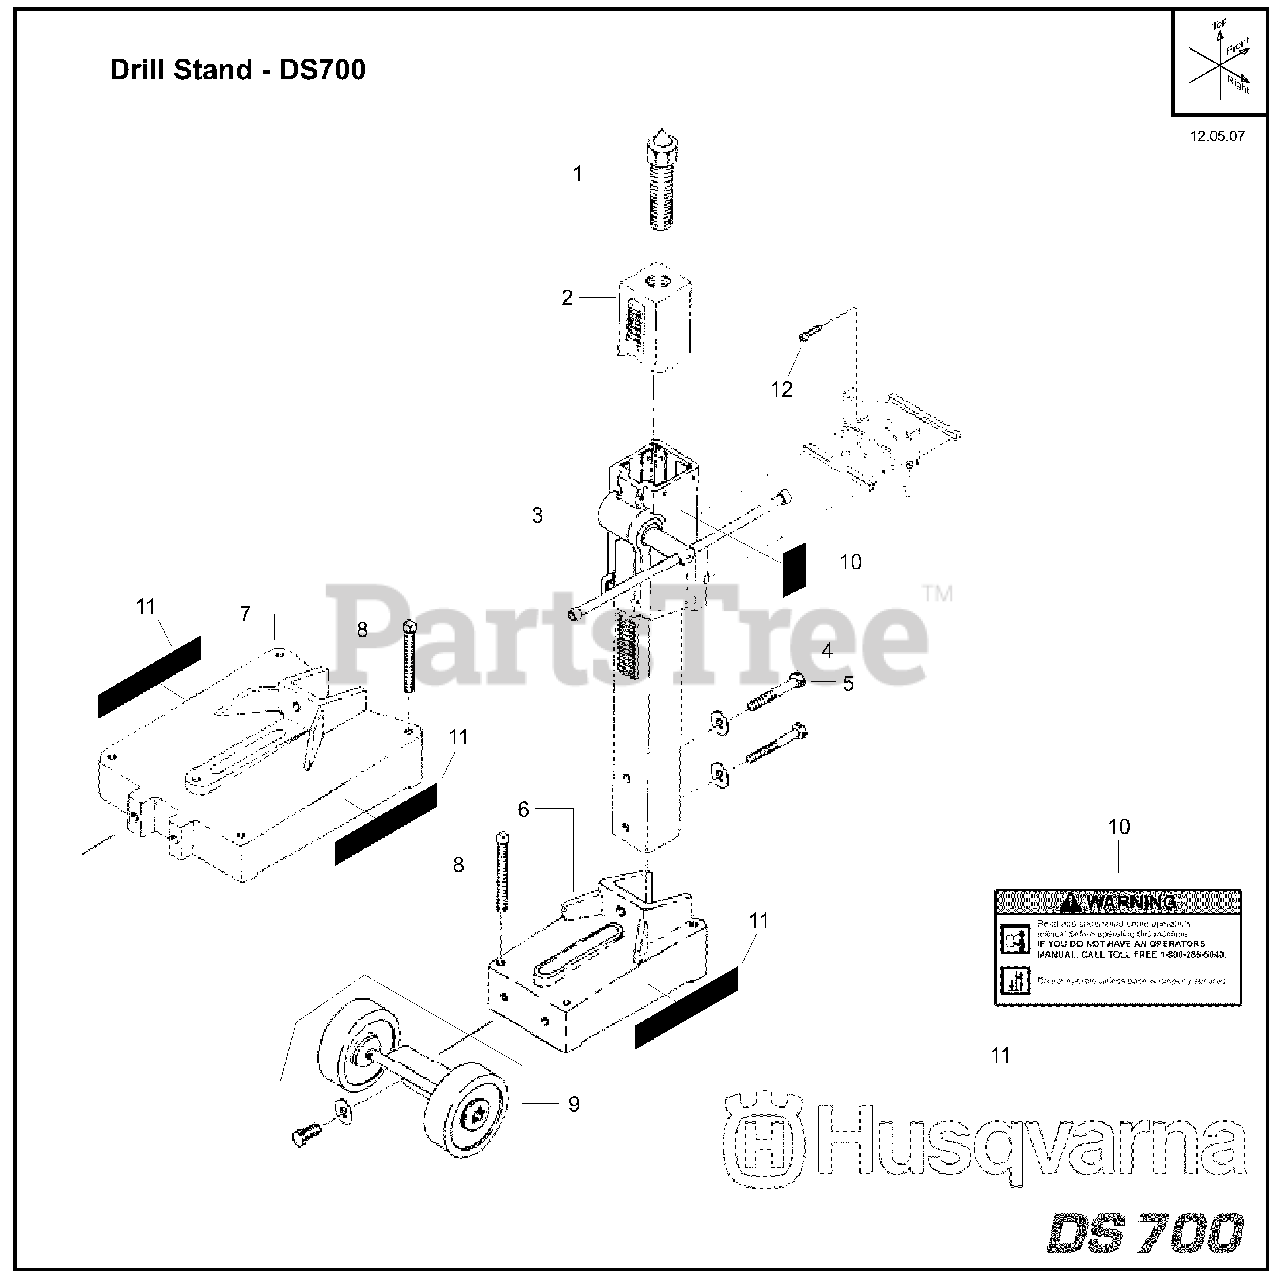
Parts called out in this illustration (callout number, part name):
1	Screw, Ceiling Jack, 1"-8UNC
2	Column w/ Rack - 2-1/2" Sq x 42"
3	Carriage, Slide - compl
4	Washer, Flat 1/2"
5	Capscrew, Hex Hd 1/2-13 x 3.25"
6	Base, Small, DS700 - Husq Orange
7	Base, Large, DS700 - Husq Orange
8	Capscrew, Sq Hd 1/2-13 x 4"
9	Axle & Wheels - compl
10	Decal, WARNING - Secure / Read
11	Decal, HUSQVARNA DS700
12	Capscrew, Soc Hd 1/4-20 x 1"
12	Capscrew, Soc Hd 1/4-28 x 1"
12	Capscrew, Soc Hd M8-1.25 x 25
